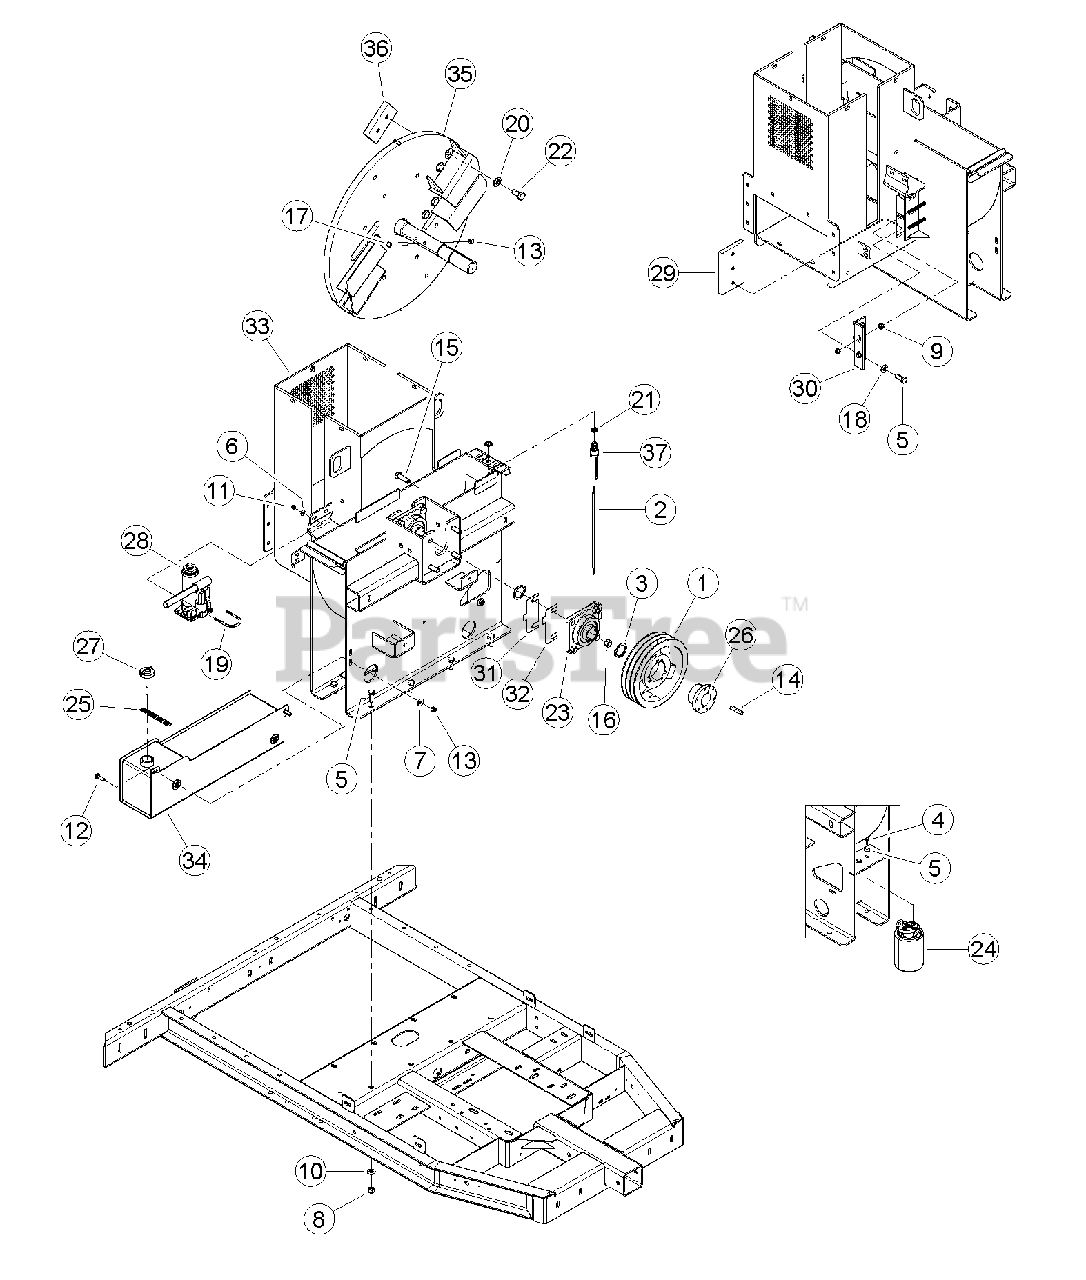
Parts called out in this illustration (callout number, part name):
1	SHEAVE, 3BQ9.4 SK
2	WIRE ASSEMBLY, ENGINE KILL
3	RING, 1-3/4 EXT HEAVY DUTY SNAP
4	BOLT, 1/4 X 3/4 HEX GR5 ZP
5	BOLT, 1/2 X 1-1/4 HEX GR5 NC ZP
6	WASHER, 1/4 FLAT ZP
7	WASHER, 3/8 FLAT ZP
8	NUT, 1/2 CENTERLOCK GRB ZP
9	NUT, 3/8 SERR FLANGE NC ZP
10	WASHER, 1/2 SAE FLAT ZP
11	NUT, 1/4 NE NYLOCK ZP
12	BOLT, 3/8 X 1-1/4 CRG GR5 NC ZP
13	NUT, 3/8 NE NYLOCK ZP
14	KEY, 3/8 SQUARE X 2 LONG PLAIN
15	BOLT, 9/16 X 1-3/4 HEX GR5 ZP
16	NUT, 9/16 CENTER LOCK GRB ZP
17	BOLT, 3/8 X 3-1/2 FULL THD GR5 ZP
18	WASHER, 1/2 HI-STRENGTH SAE ZP
19	U-BOLT, 1/4 X 1-1/2 PIPE
20	WASHER, 5/8 SAE HARDENED
21	NUT, 5/8-32 JAM
22	BOLT, M16 X 2.0 X 30 HEX HD W/PATCH
23	BEARING, 1-3/4" 4 BOLT FLANGE
24	ASSEMBLY, HYDRAUILC FILTER
25	DECAL, HYDRAULIC FLUID
26	BUSHING, SK 1-3/4"
27	CAP, HYDRAULIC W/ DIPSTICK
28	JACK, HYDRAULIC 2 TON
29	ANVIL, 6" CHIPPER
30	WELDMENT, BLOCK ADJUSTOR
31	SHIM, 20 GA.
32	SHIM, 16 GA.
33	WELDMENT, 6 IN CHIPPER HOUSING
34	WELDMENT, HYDRAULIC TANK
35	WELDMENT, 6 CHIPPER DISK
36	BLADE, BIG CHIPPER
37	ASSEMBLY, SEALED SWITCH
